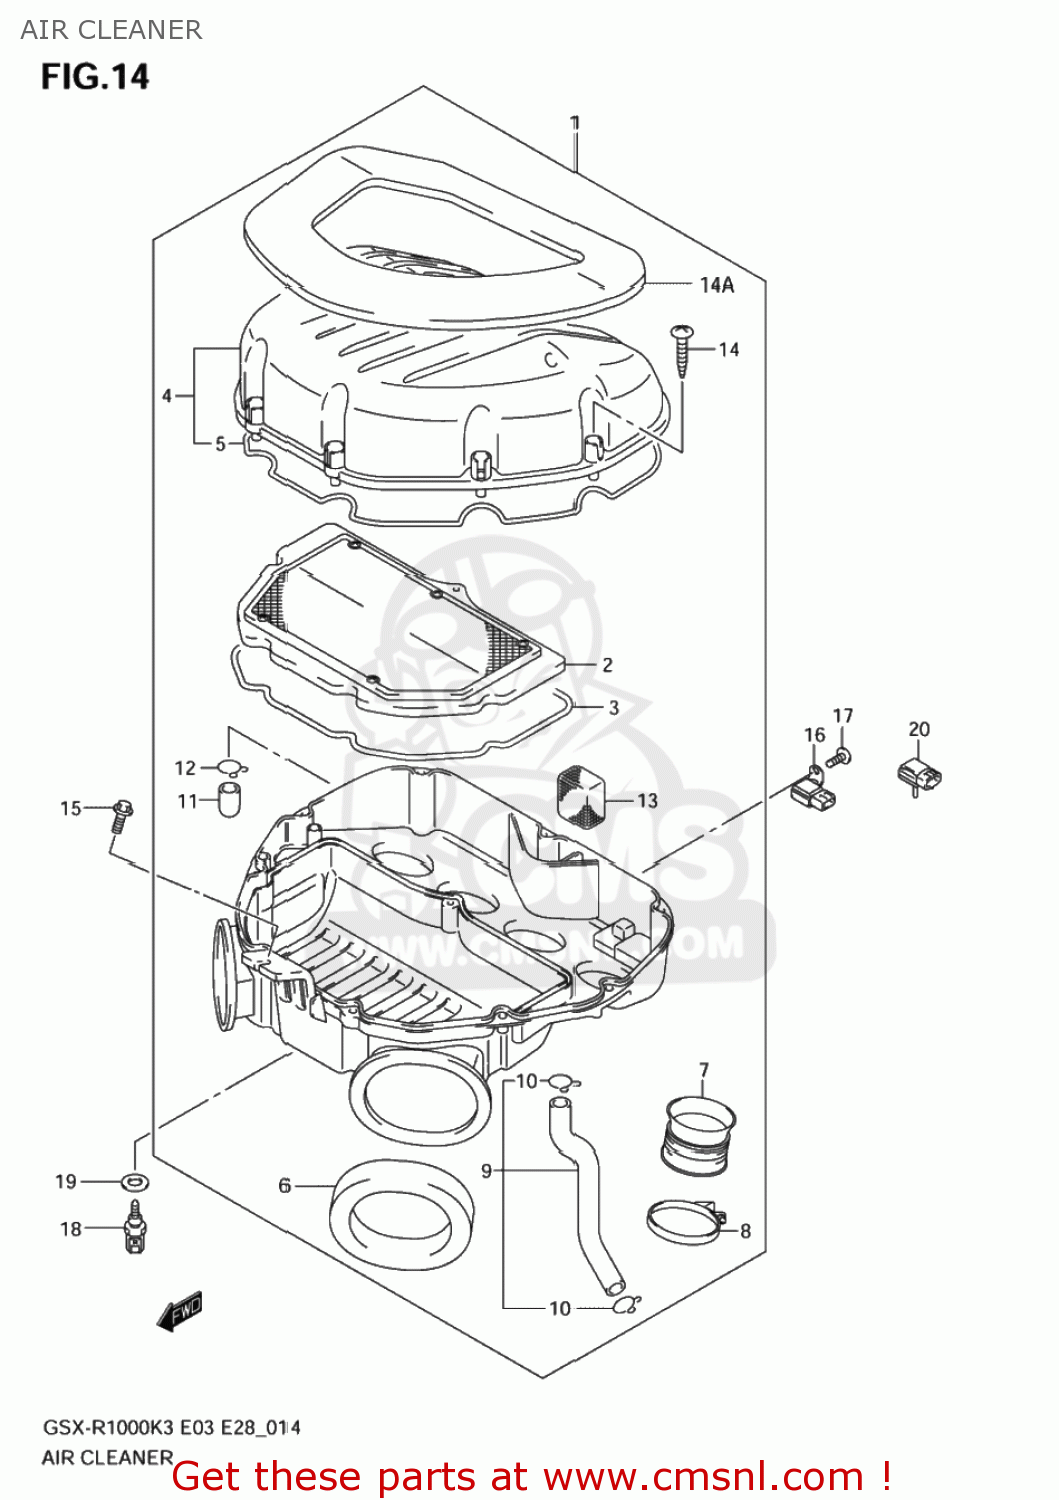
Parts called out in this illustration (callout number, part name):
1	CLEANER ASSY,AIR
2	FILTER ASSY,AIR CLEANER
3	GASKET,CASE (NAS)
4	CAP,AIR CLEANER
5	GASKET,CAP (NAS)
6	CUSHION,DUCT
7	TUBE,OUTLET
8	CLAMP
9	TUBE,BREATHER
10	CLIP
11	PLUG
12	CLIP
13	FILTER,BREATHER
14	SCREW
14A	SHEET,CAP NO.1
15	BOLT(6X16)
16	SENSOR,BOOST
17	SCREW HEADLAMP
18	SENSOR,WATER TEMP
19	GASKET(12X17X1) (NAS)
20	SENSOR,AIR PRESSURE
